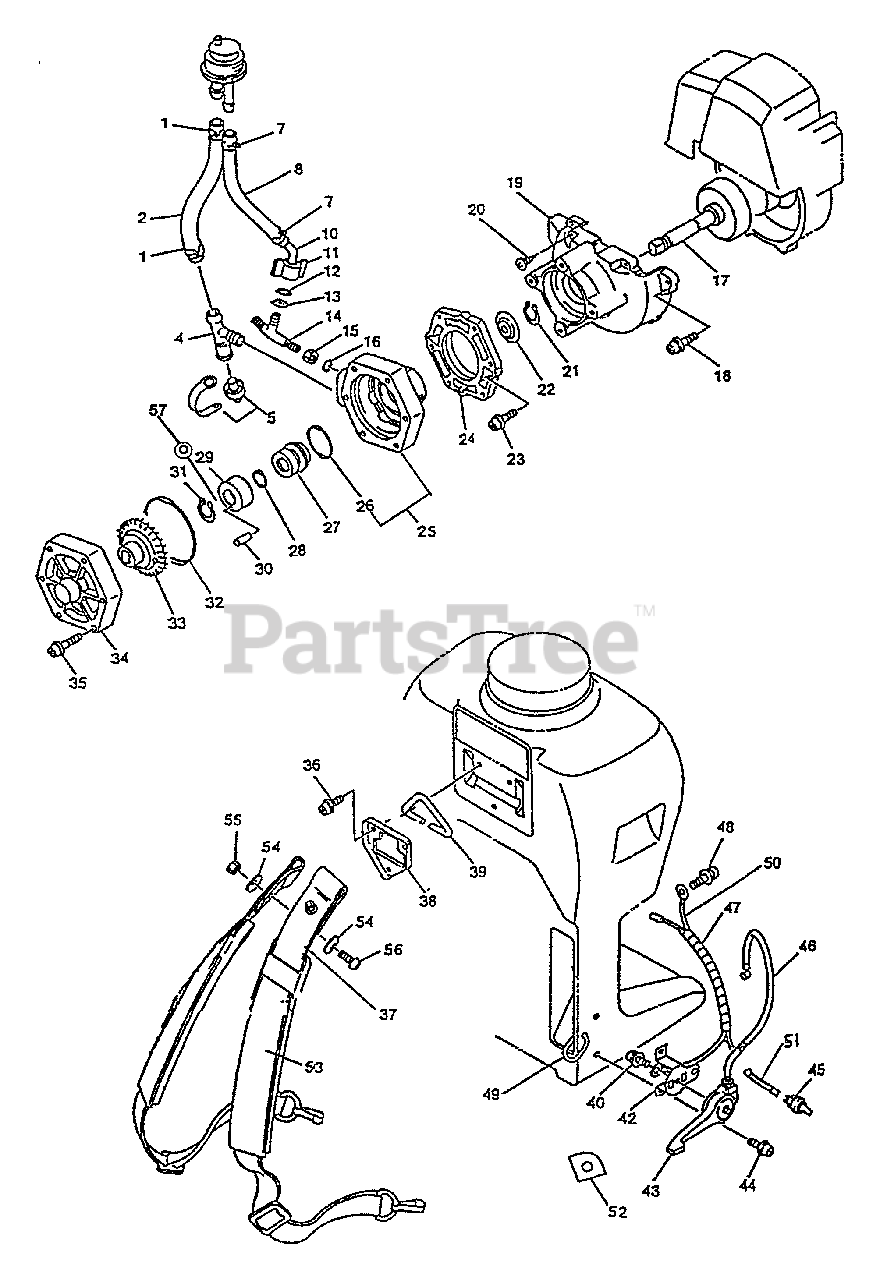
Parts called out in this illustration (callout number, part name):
2	HOSE, FLUID
5	DRAIN PLUG KIT
7	CLIP - 10
8	HOSE, FLUID
10	JOINT, BYPASS
11	WINGNUT
12	GASKET, BYPASS NOZZLE
14	NIPPLE, OUTLET PUMP
16	O-RING - 10
17	DRUM, CLUTCH
18	SCREW - 4X16
19	CASE, FAN
20	SCREW - 4X16
21	RING, RETAINING - 12
22	PLATE, SEAL
23	SCREW - 6X16
24	BRACKET, PUMP
25	CASE, PUMP
26	O-RING - 29
28	O-RING - 10
29	SEAL
31	RING, RETAINING - 12
32	O-RING
33	IMPELLER
34	LID, PUMP
35	SCREW - 5X40
36	SCREW - 6X10
37	STRAP, BACKPACK
38	BRACKET, HANGER
40	SCREW - 5X10
42	BRACKET, THROTTLE
43	LEVER, THROTTLE
44	SCREW - 5X16
45	IGNITION SWITCH ASSY
46	CABLE, THROTTLE
47	WRAP, SPIRAL
48	SCREW - 5X10
49	RING, STRAP
50	LEAD - GROUND
51	LEAD - GROUND
52	LABEL - SWITCH
53	PAD, STRAP
55	LOCKNUT - 5
56	SCREW - 5X14
